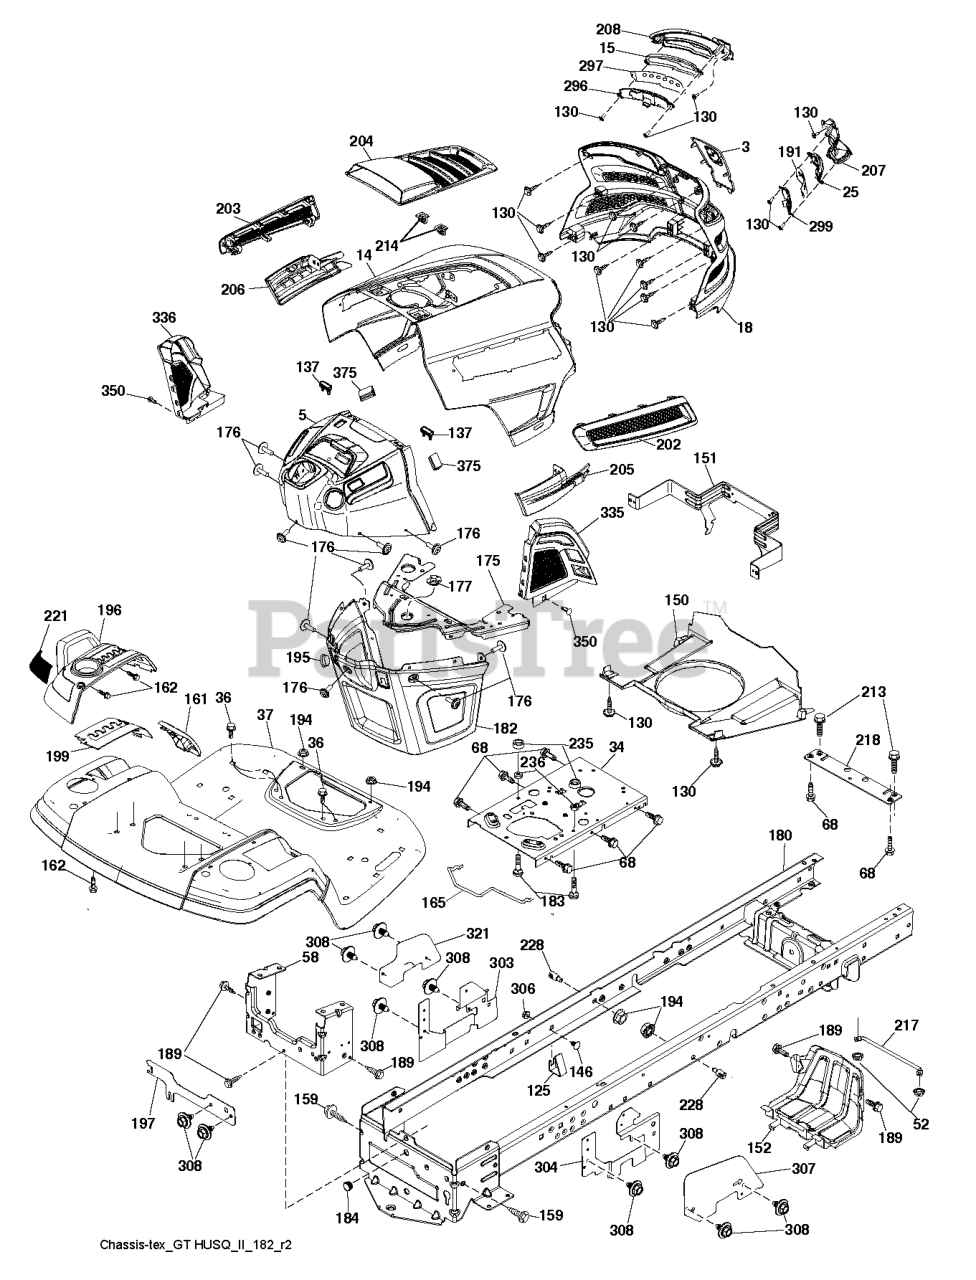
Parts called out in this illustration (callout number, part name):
3	APPLIQUE.SUBASM.GT.HUSQ.II
5	DASH.GT2.RND.EL.1ACC.RS.498
14	HOOD.ASM.HUSQVARNA.GT.TEX.ORAN
15	LED LIGHT.LH
18	GRILLE.SUBSTRATE.2011.
25	LENS.RH
34	PLATE.ENGINE.WELDED.CHASSIS
36	SCREW 5/16"
37	FENDER.PNT.TX.GT.CH/FW/DL.HUSQ
52	LOCKNUT
58	DRAWBAR.UPPER.2PC,LRG.FENDER
68	Screw 5/16-18 x 1/2 Hex, Self Tapping 5/16-18 x 1/2
125	CLIP.FUEL.LINE
130	SCREW.#10 X 0.750.BOS
137	BUMPER DASH
146	BOLT.RDHD.SHT.SQNK.3/8-16X5/8
150	AIR.DUCT.GTV.BLACK
151	BRACKET.PIVOT.HOOD.GT.HUSQ.II
152	SHIELD.BROWNING.PNT.GT.V2
159	SCREW, 3/8-16X3/4
161	CONSOLE.WINDOW.FUEL.HUSQ.GT
162	SCREW.HI-LO.CONSOLE
165	SUPPORT.TANK.REAR.W/TEX
175	PLATE.CROSSMEMBER.HUSQ
176	SCREW.#10-24X5/8.RN.QU
177	BUSHING, STEERING
180	CHASS.WLDMNT.TLT.12GA/2PC.20"
182	DASH.LOWER.COMMON.12V.ADAPTOR
183	BOLT.5/16-18X1-1/4 FULL THD
184	PLUG.DEMO.625
189	SCREW
191	INSERT INFLECT.RH
194	NUT LOCK HEX FLANGE 5/16-18
195	PLUG.HOLE.DASH.LOWER.12V.BLK
196	SUBASM.CONSOLE.HUSQ.GT.DECKLFT
197	SHIELD.DRAWBAR.LT.REAR.TANK
199	PLATE.DECK.LIFT.HUSQVARNA.GT
202	VENT.SIDE.RH.GT.HUSQ.II.
203	VENT.SIDE.LH.GT.HUSQ.II.498
204	VENT.TOP.HUSQ.GT2
205	SIDE.TRIM.RH.GT.HUSQ.II
206	SIDE.TRIM.LH.GT.HUSQ.II.GRAY
207	LIGHT.BEZEL. RH
208	LIGHT.BEZEL.LH
213	BOLT
214	CLIP.RETAINER.TINNER.
217	ROD.PIVOT.HOOD
218	X-PIECE.HOOD.STOP.NON/
221	REFLECTOR.LH.TEX GT HU
228	STUD.FASTNER.W/ANTI-ROTATE
235	SPACER FENDER
236	NUT.CENTERLOCK.5/16-
296	LED LIGHT.LH
297	INSERT REFECT LH
299	LED LIGHT.RH
303	SHIELD CHASSIS LEFT
304	SHIELD.RH.LOW.LT/GT.NON-30.PNT
306	NUT LOCK FLG 3/8-16 UNC
307	SHIELD UPPER PEDAL
308	BOLT.5/16-18UNCX3/4 W/SEMS.BLK
321	SHIELD.UPPER.LH.GT
335	COVER.LOWER.DASH.RH.BLACK
336	COVER-LH.LOWER.DASH.GT2.BLACK
350	CLIP.X-MAS.TREE
375	BUMPER CLIP-ON. DASH 1"
